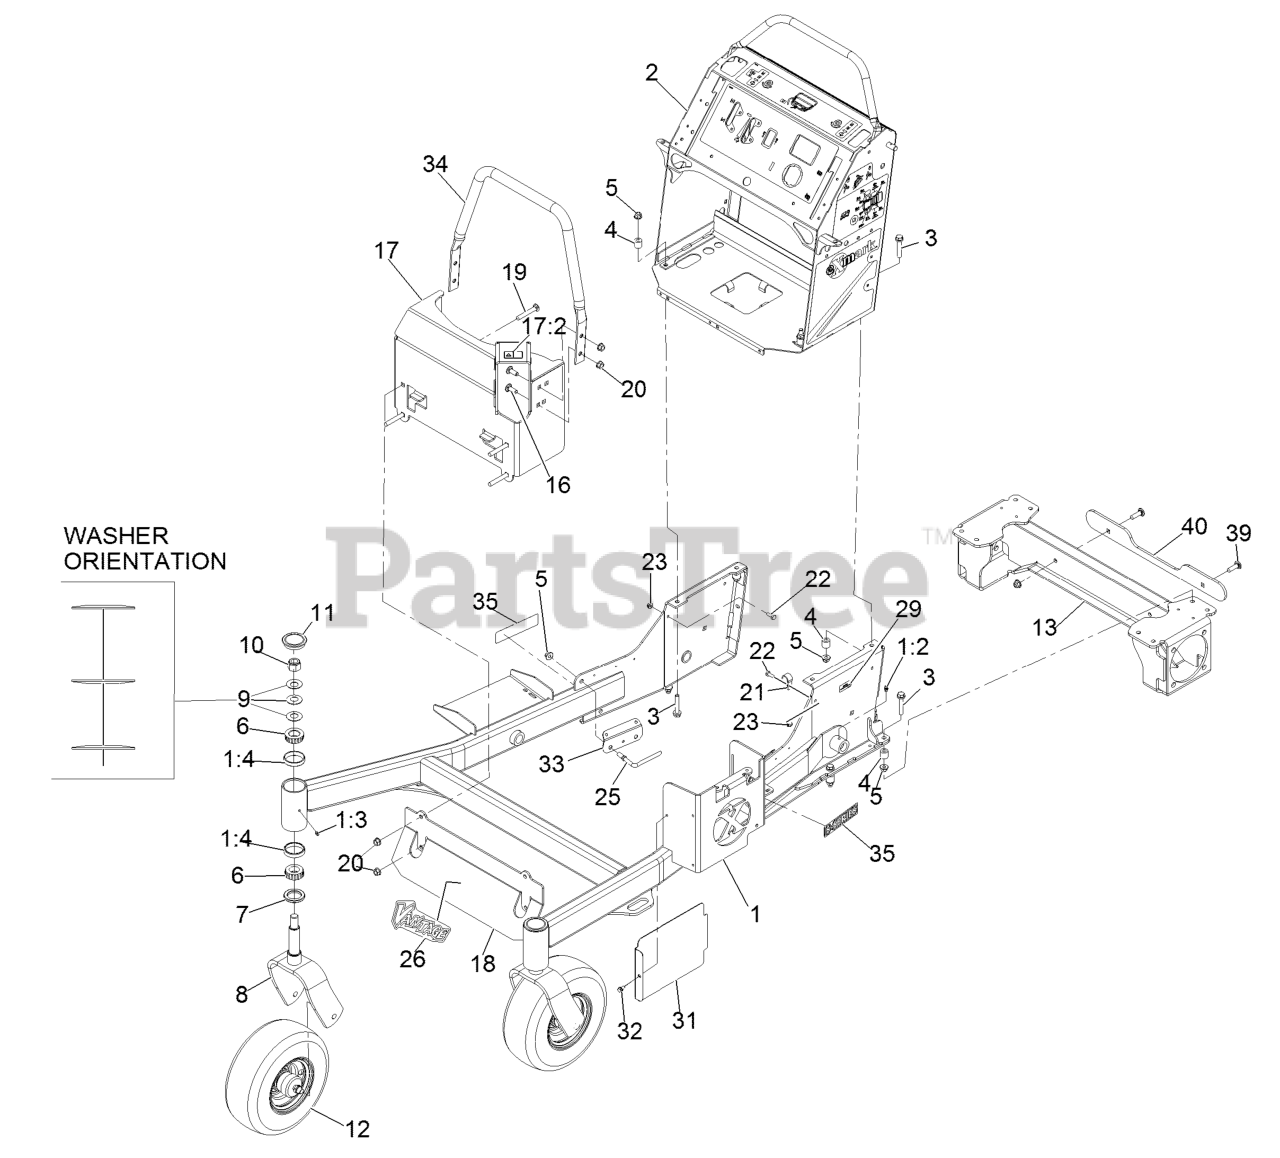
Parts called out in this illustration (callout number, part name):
1	FRONT FRAME ASM
1:2	FITTING-GREASE
1:4	CUP-BEARING
2	CONTROL TOWER ASM-EFI
3	SCREW-HHF
5	NUT-HF, NI
6	Cone-Bearing Tapered Roller
7	SEAL-GREASE
8	FORK-CASTER
9	WASHER-BELLVILLE
10	NUT-LOCK, NI
11	CAP-GREASE
12	WHEEL/TIRE AND BEARING AS
13	WELD, MOTOR FRAME
16	SCREW-CARR
17	ASM, MUFFLER GUARD W/ DEC
17:2	DECAL-WARNING
18	PANEL-GUARD
19	SCREW-CARR
21	CLAMP-CABLE
22	SCREW-HH
25	GUIDE-HOSE, SUPPORT
26	DECAL-VANTAGE LOGO
29	Decal-Patent Ttco.Com
31	SHIELD-HEAT, TALL
32	SCREW-HWH
33	GUARD-HOSE
34	TUBE-GUARD
35	DECAL-S-SERIES
39	SCREW-CARR
40	PLATE, BUMPER SPACER
